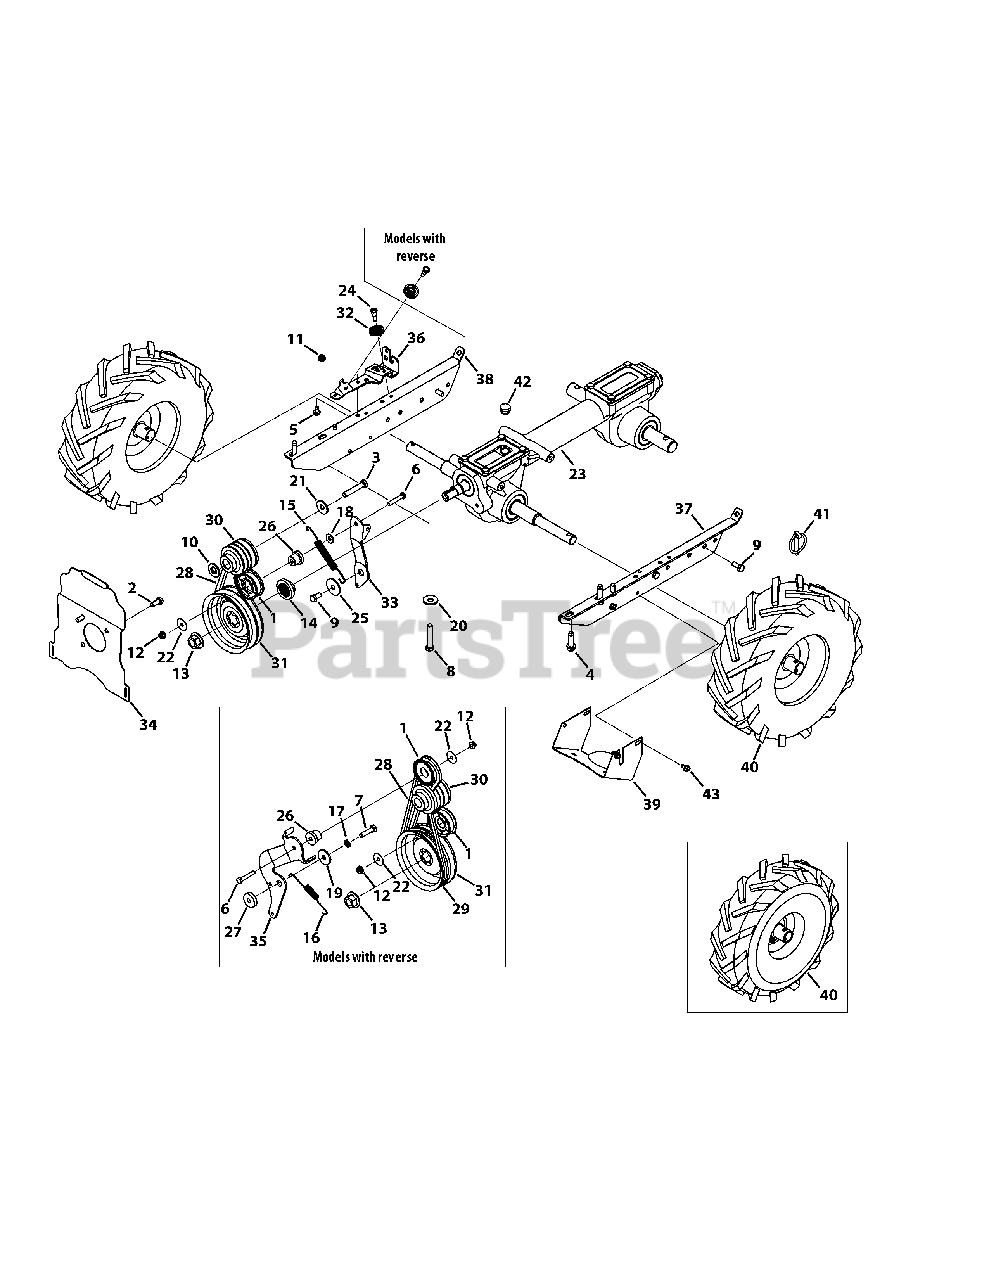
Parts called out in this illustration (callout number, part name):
1	Idler Pulley Assembly, 1917 OD
2	Hex Head Screw, 5/16-24 x 625
3	Hex Head Screw, 3/8-24 x 200
4	Screw, 3/8-16 x 1250
5	Screw, 1/4-20 x 0500
6	Hex Head Screw, 1/4-20 x 150
7	Hex Head Screw, 5/16-24 x 125
8	Hex Head Screw, 5/16-18 x 150, B&S
9	Hex Head Screw, 5/16-18 x 75, Patch
10	Washer, Flat, 760 x 150 x 120
11	Flangelock Nut, 5/16-18, B&S
12	Flangelock Nut, 1/4-20
13	Flange Nut, 9/16-18
14	Pulley Hub, 5/8 SPLINE
15	Extension Spring, 480 OD x 500 LG
16	Extension Spring, LT5 PTO
17	Washer, Lock, 5/16
18	Washer, Flat, 28 x 74 x 063
19	Washer, Flat, 330 x 125 x 120
20	Washer, 396 x 1140 x 095, B&S
21	Washer, Bell, 396 x 1140 x 095
22	Washer, Flat, 265 x 10 x 030
23	Transmission Assembly
24	Screw, Shoulder, 1/4-28 x 342 x 335
25	Forward Idler Pivot Spacer
26	Spacer, Shoulder, 260 x 785 x 538
27	Reverse Idler Pivot Spacer
28	V Belt, 4L x 25375 LG
29	V Belt, 3L x 29125 LG
30	Engine Pulley, 3L & 4L, Honda
31	Transmission Pulley
32	Cable Roller
33	Forward Idler Bracket
34	Cover Mounting Plate
35	Reverse Idler Bracket
36	Pulley Mounting Bracket
37	LH Mount Frame
38	RH Mount Frame
40	Wheel, 13 x 5 x 6
41	Klik Pin, 25 DIA x 156
43	Self Tapping Screw, 1/4-14 x 625
